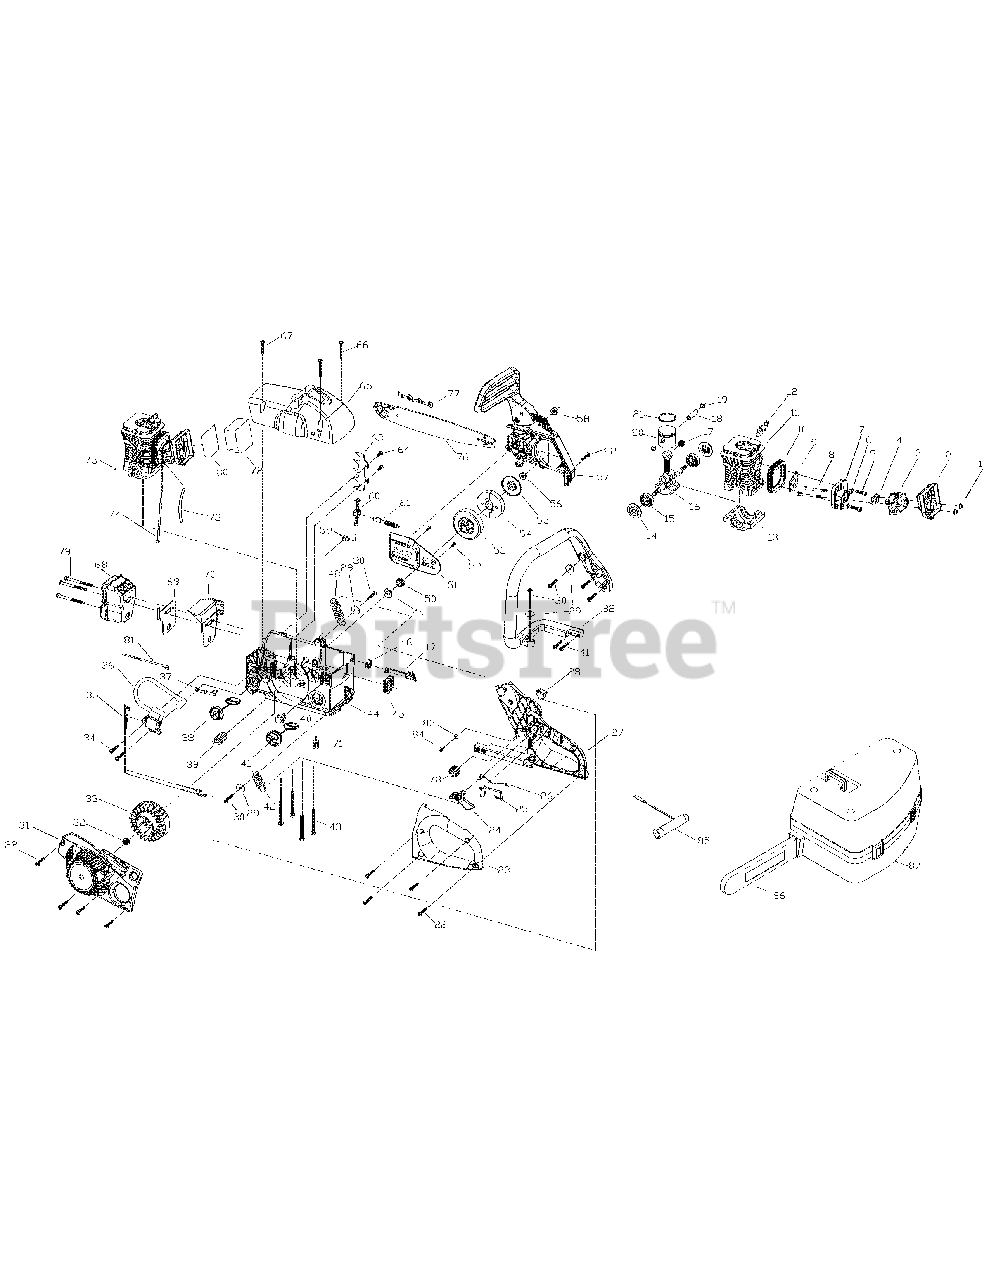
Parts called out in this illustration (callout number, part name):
1	NUT
2	AIR FILTER ASS/Y
3	CARBURETOR
5	SCREW
6	SPRING WASHER
7	ISOLATOR, CARBURETOR
8	SCREW
10	RUBBER, ISOLATOR
11	CYLINDER
12	SPARK PLUG
13	CASE, CRANK
14	CAP, BEARING
15	BEARING
16	CRANK/ROD ASS'Y
17	ROLLER, PISTON
18	PIN, PISTON
20	PISTON
21	RING, PISTON
23	HANDLE, LEFT PART
24	TRIGGER, THROTTLE
25	TRIGGER, RELEASE
27	HANDLE, REAR
28	SWITCH
29	WASHER
31	STARTER HOUSING ASS'Y
32	NUT
33	FLYWHEEL
34	SCREW
35	WIRE ASS'Y
36	IGNITION ASS'Y
37	CONDUCTIVE PLATE
38	OIL CAP ASS'Y
39	SPRING ASS'Y
41	FUEL CAP ASS'Y
42	SPRING
43	SCREW
44	HOUSING ASS'Y
45	HOLDER, CABLE
46	HOLDER, CHOKE LEVEL
47	LEVER, CHOKE
51	CAP, ANTI-DUST
53	DRUM ASS'Y
54	CLUTCH ASS'Y
55	CAP, ANTI-DUST
56	NUT
57	BRAKE KIT ASS'Y
58	NUT
59	CONNECTOR
60	OIL PIPE
61	PUMP ASS'Y
63	SPIKED BUMPER
64	SCREW
66	SCREW
67	SCREW
68	MUFFLER ASS'Y
72	FILTER, AIR
73	FUEL PIPE
74	CABLE, THROTTLE
75	WOODRUFF KEY
78	RUBBER
81	BIND BAND
82	HANDLE, FRONT
85	WRENCH
86	SCABBARD
87	CARRY CASE
